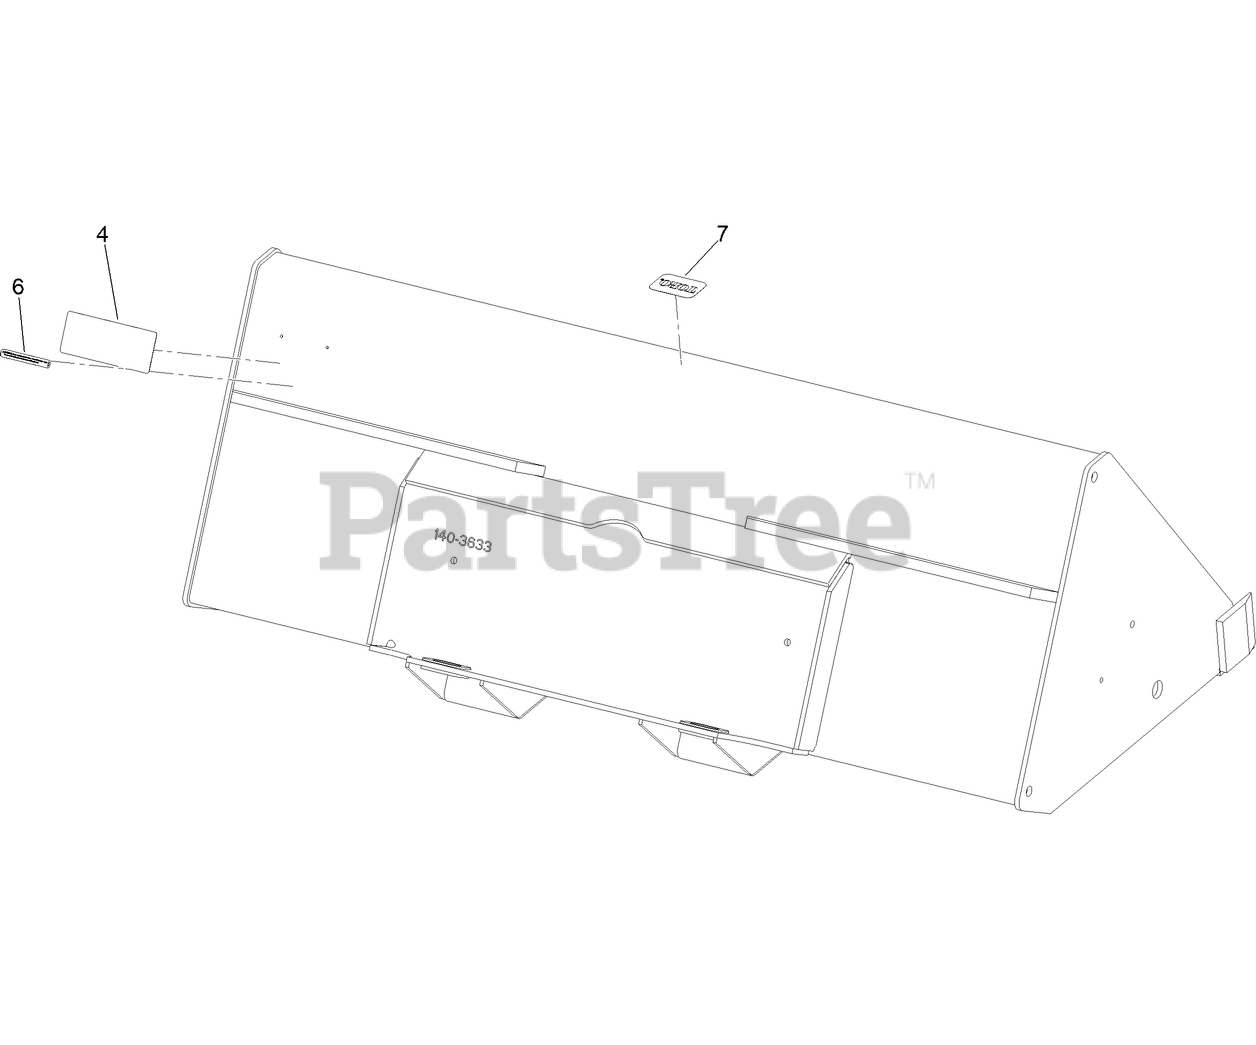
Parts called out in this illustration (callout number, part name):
4	DECAL-CAPACITY
6	DECAL-WARNING
7	DECAL
